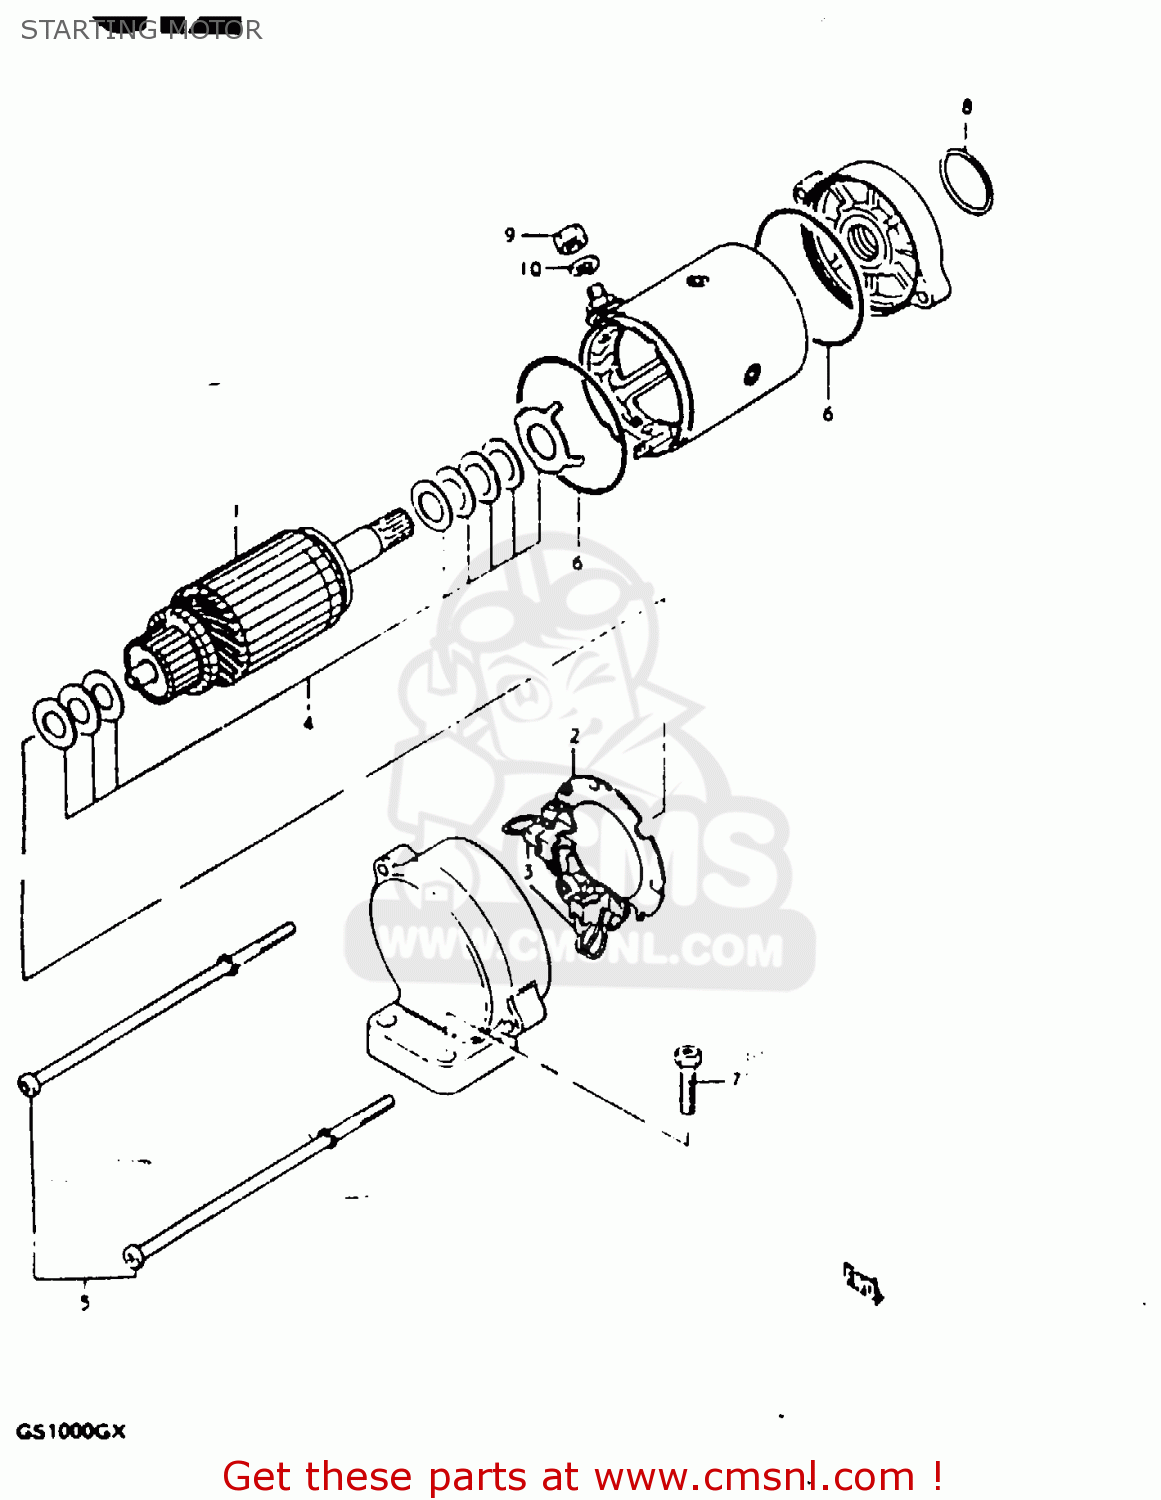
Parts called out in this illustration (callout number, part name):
1	ARMATURE
2	HOLDER ASSY
3	BRUSH SET
4	SHIM SET
5	BOLT,STARTING MOTOR HOUSING
6	O RING
7	SCREW (6X25)
8	O RING(D:2,ID:24.5)
9	NUT 6MM
10	LOCK WASHER
